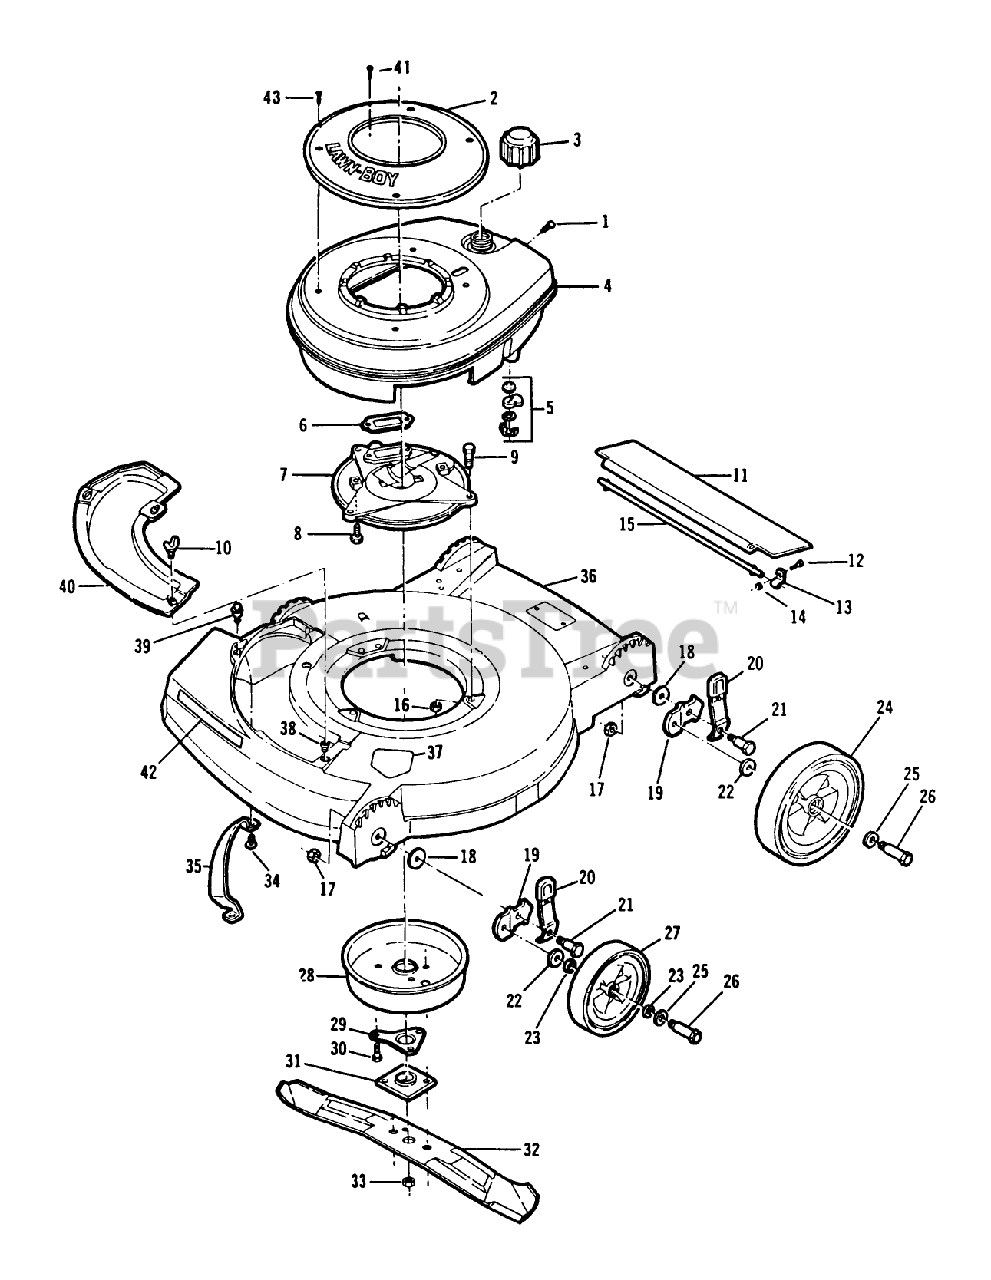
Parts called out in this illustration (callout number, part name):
1	SCREW S
3	FUEL CAP & INSERT
5	SHUT OFF VALVE KIT
7	PLATE F
8	SCREW V
9	SCREW-HH
10	WING SCREW LAWRE
13	CLAMP ROD KMC
14	LOCKNUT E
15	ROD T/SHIELD ADV WIRE
16	NUT-LOCK F
17	LOCKNUT
18	WASHER
20	SPRING ARM ASM
21	BOLT
22	WASHER WROUGHT
23	Felt Washer
24	WHEEL&TIRE 8" TRI
25	SPACER
26	BOLT WHEEL
28	MUFFLER COVER F
29	SUPPORT F
30	SCREW
31	PLATE AND COLLAR ASM
33	NUT-BLADE
35	TOE BAR 19"
41	SCREW SEMS SM
43	SCREW - SELF TAPPING
